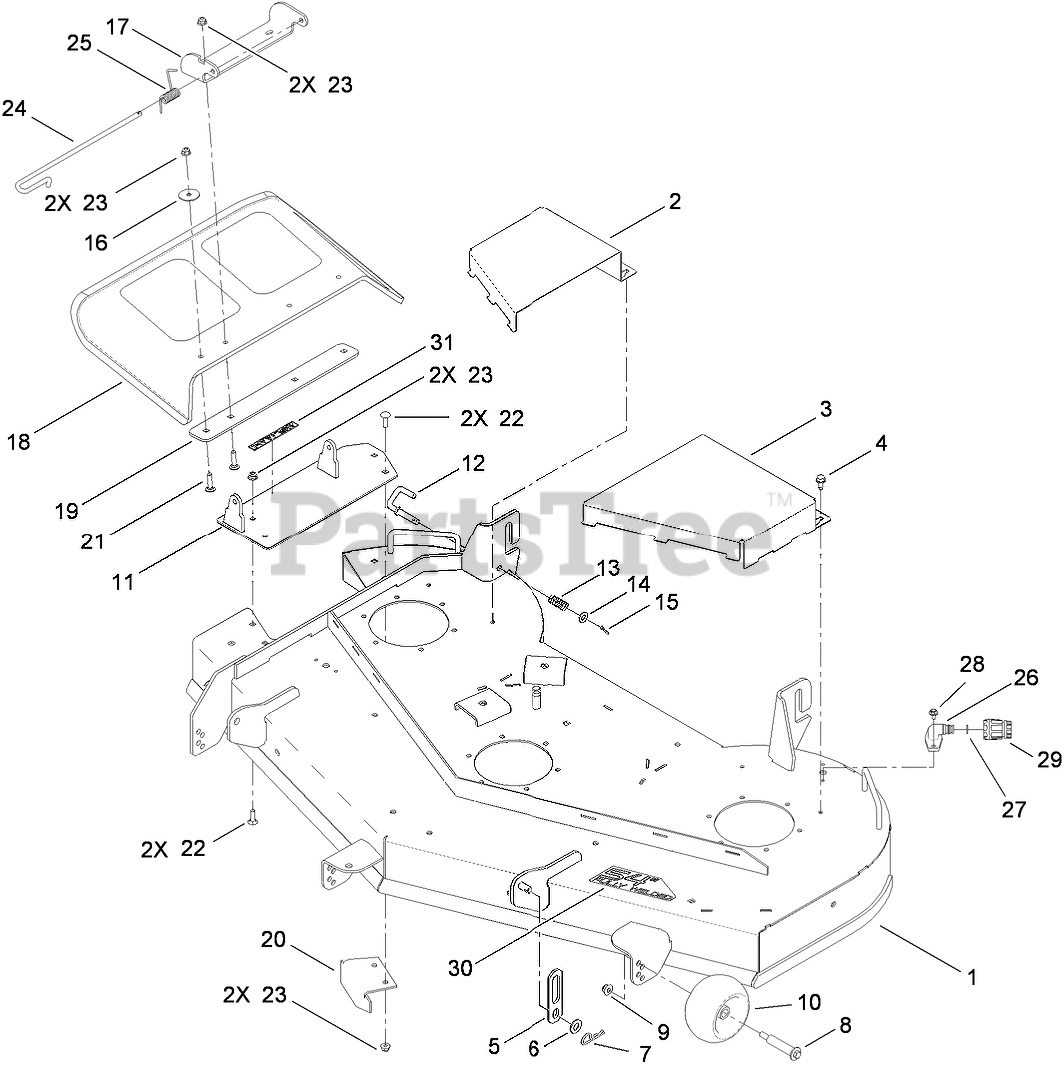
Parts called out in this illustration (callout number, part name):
1	54 INCH DECK ASM
2	COVER-BELT, RH
3	COVER-BELT, LH
4	SCREW-HWHTF
5	LINK-LIFT
6	WASHER-FLAT
7	PIN-COTTER
8	BOLT-SHOULDER
9	NUT-HF, NI
10	ROLLER-SCALP, ANTI
11	PLATE-COVER
12	PIN-LATCH
13	SPRING-COMPRESSION
14	WASHER-FLAT
15	PIN-COTTER
16	WASHER-FLAT
17	BRACKET-DEFLECTOR, UPPER
18	DEFLECTOR
19	PLATE-DEFLECTOR
20	BAFFLE-CUTOFF
21	SCREW-CARR
22	SCREW-CARR
23	NUT-HF, NI
24	PIN-CHUTE
25	SPRING-TORSION
26	FITTING-WASHOUT
27	O-RING
28	SCREW-HHFTF
29	CONNECTOR-HOSE
31	DECAL-DANGER
